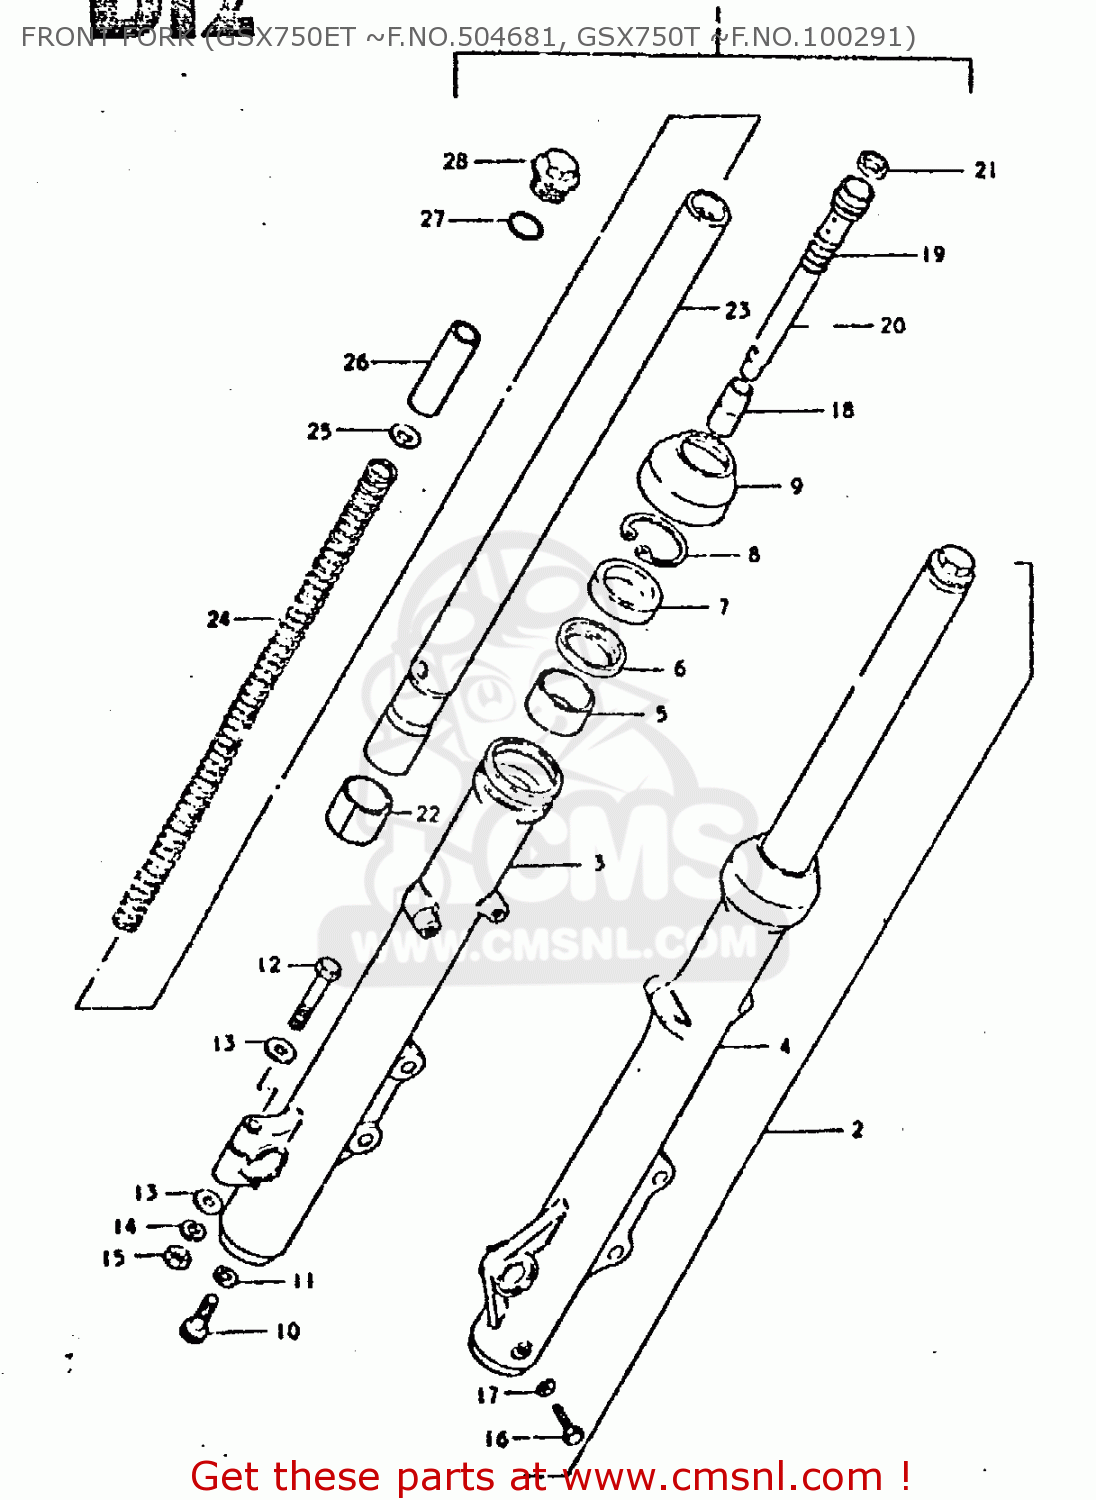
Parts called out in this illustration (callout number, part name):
1	DAMPER ASSY, RH
2	DAMPER ASSY, LH
3	TUBE,FORK,OUTER,RIGHT
4	TUBE,FORK,LEFT,OUTER
5	BUSH,GUIDE
6	SPACER,SEAL
7	OIL SEAL,FRONT FORK
8	CIRCLIP,FORK OIL SEAL
9	BOOT
10	BOLT(8X27)
11	GASKET (NAS)
12	BOLT 8X50
13	WASHER
14	LOCK WASHER
15	NUT
16	BOLT(6X8)
17	GASKET,DRAIN,PLUG (NAS)
18	PIECE,OIL LOCK
19	SPRING,FORK REBOUND
20	CYLINDER
21	RING, PISTON
22	PISTON
23	TUBE,FORK,INNER
24	SPRING
25	WASHER,SPRING
26	SPACER (L:50)
27	O-RING
28	CAP,INNER TUBE
